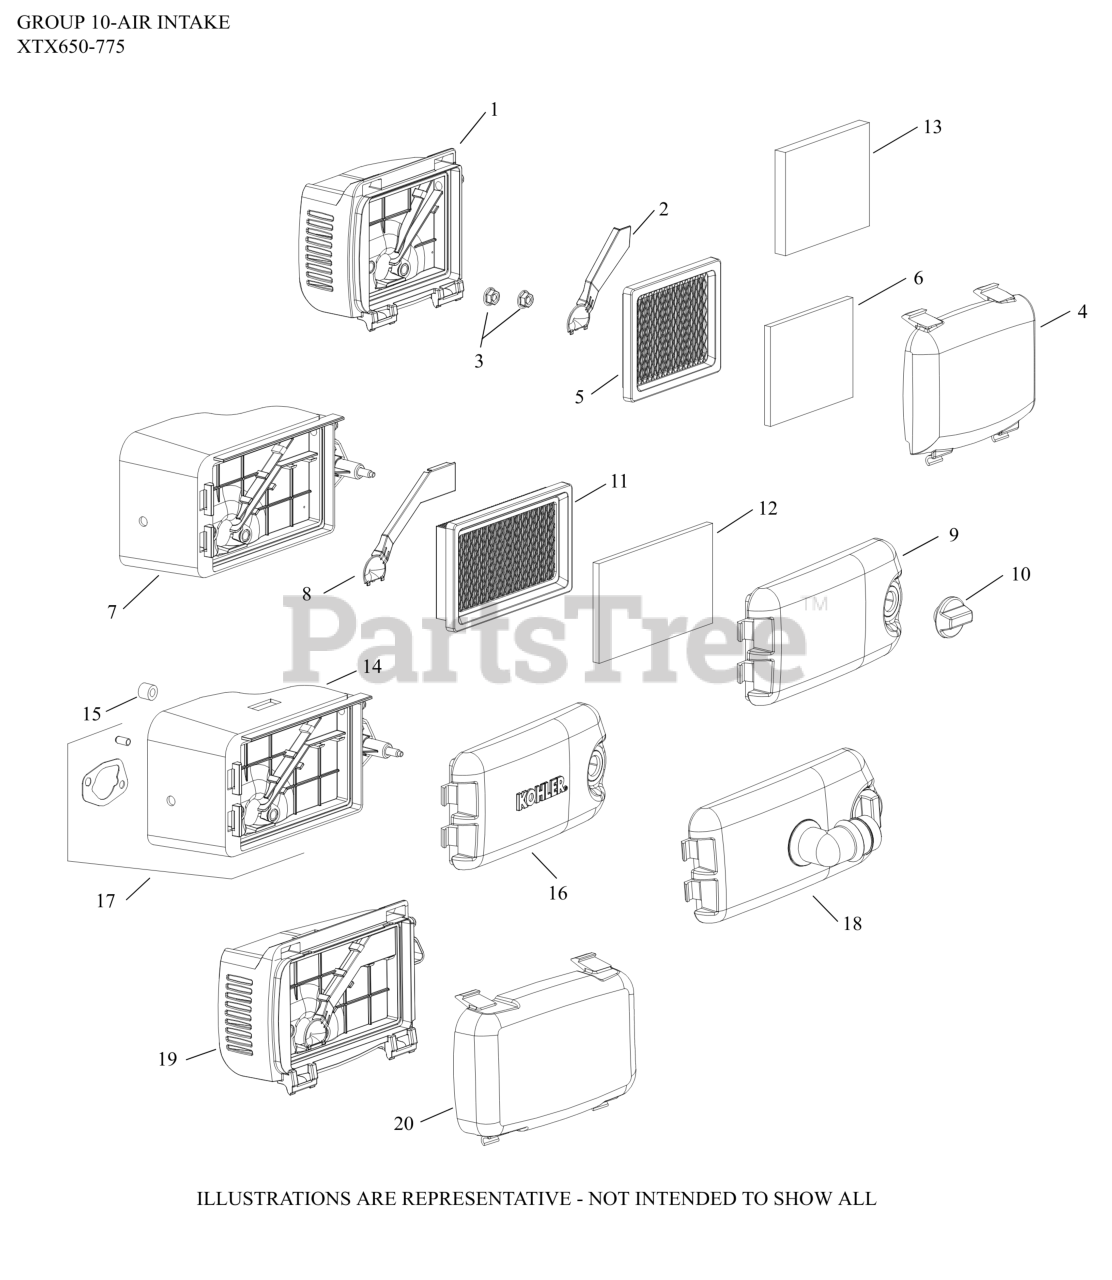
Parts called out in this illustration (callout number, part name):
8	COVER, A/C BASE (BREATHER GAS)
11	ELEMENT, FOAM FILTER
19	BASE, AIR CLEANER
20	COVER, AIR CLEANER BASE
